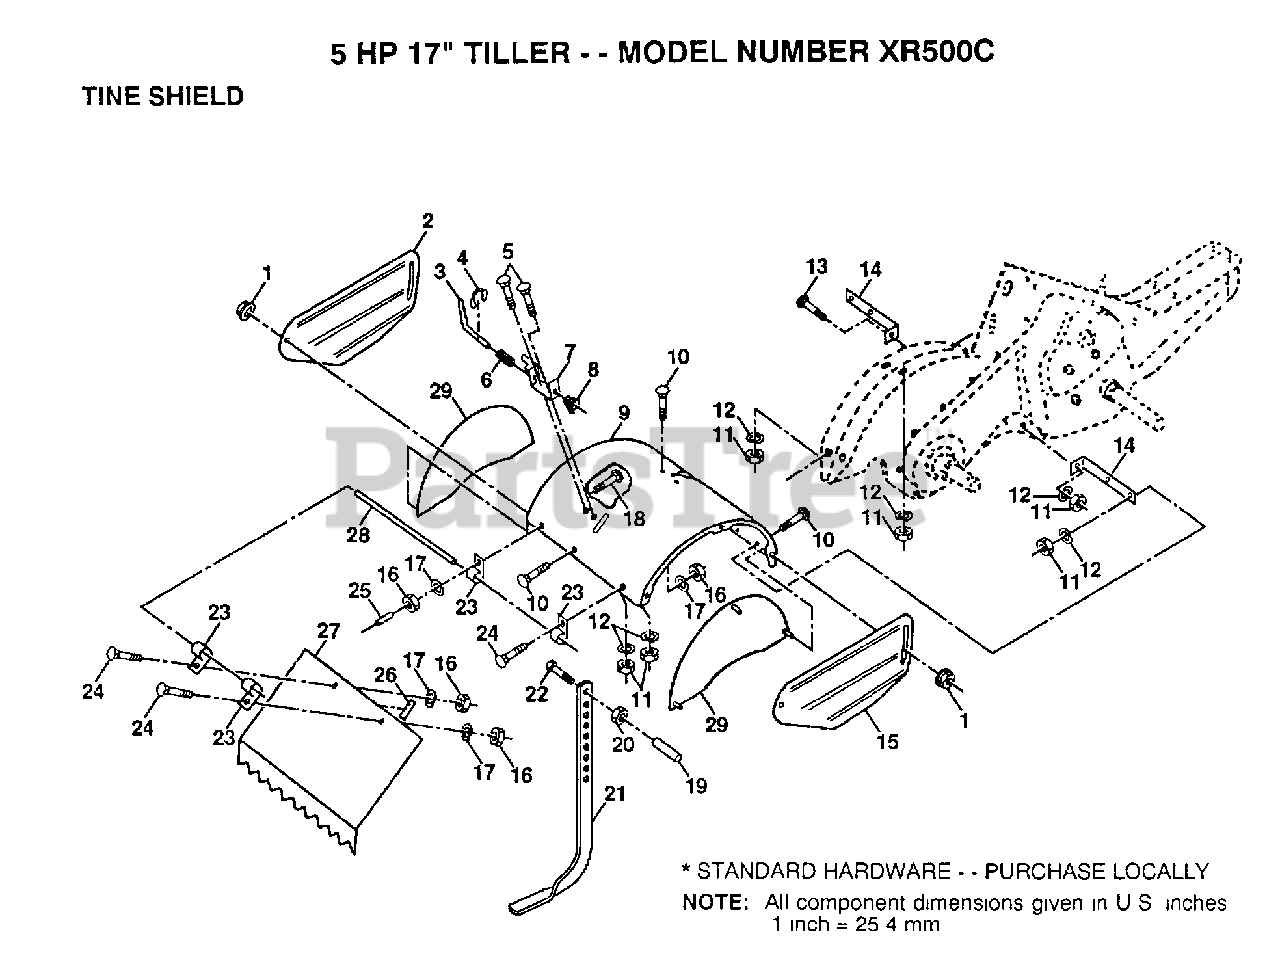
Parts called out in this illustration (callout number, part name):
1	NUT
2	SHIELD.SIDE.OUTLH
3	STAKE PIN TI
4	KLIP RING TI
5	BOLT CRT
6	SPRING TI
7	LATCH BRACKET TI
8	SPRING CRT
9	"SHIELD,TINE TI"
10	BOLT
11	NUT.HEX.5/16-18
12	LOCKWASHER
13	BOLT
14	BRKT SHIELD TINE
15	SHIELD.SIDE.OUTRH
17	LOCKWASHER
18	BOLT
19	GRIP CRT
20	NUT.HEX.3/8-16UNC
22	BOLT
23	HINGE CRT
24	BOLT
25	VINYL CAP TI
26	PAD IDLER TI
27	"SHIELD, LEVEL TI"
28	PIN HINGE
29	"SHIELD,SIDE TI"
